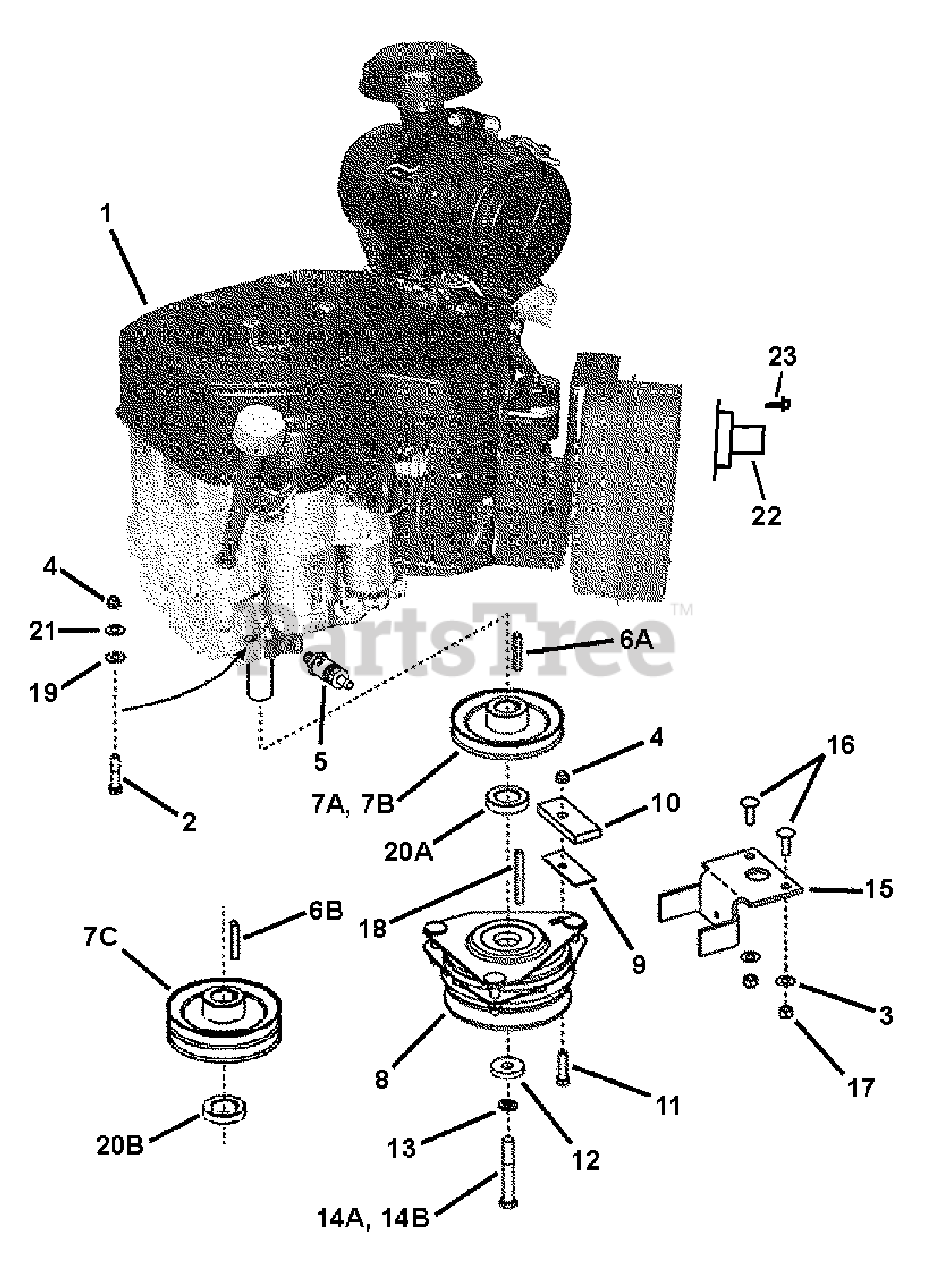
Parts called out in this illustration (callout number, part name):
2	SCREW, 5/16-18 x 1-1/2" Hex Head Cap, GR 5
3	RETAINER, 3/8" Bolt
4	NUT, 5/16-18 Hex Top Lock, GR B
5	ASSEMBLY, Oil Valve
6A	KEY, 1/4" Square x 1-1/4" Long
6B	KEY, 1/4" Square x 1" Long
7A	PULLEY, Engine, Hydro Drive
7B	PULLEY, Engine, Hydro Drive
7C	PULLEY, Engine (Double)
8	CLUTCH, Electric (Ogura GT-2)
8	CLUTCH, Electric (Ogura GT-2.5)
9	WASHER, Rectangular Steel
10	BUMPER, Electric Clutch
11	BOLT, 5/16-18 X 1-1/4 GD5 YZ
12	WASHER, .468 x 1.85 x .25 Flat
13	WASHER, 7/16" Split Lock
14A	BOLT, 7/16-20 X 3" GD5
14B	SCREW, 7/16-20 x 2-1/2" Hex Head Cap, GR 5 (w/Nyloc Patch)
15	BRACKET, Clutch
16	BOLT, 3/8-16 x 1" Square Neck Carriage, GR 5
17	NUT, 3/8-16 HEX NYLON LOCK
18	KEY, 1/4" Square x 2-1/4" Long
19	RETAINER, 5/16" Bolt
20A	SPACER, Ogura Clutch
20B	SPACER, Clutch
21	WASHER, 5/16" Flat
22	OUTLET, Muffler
23	SCREW, # 8-18 x 1/2" Hex Washer Head Self-Tap
